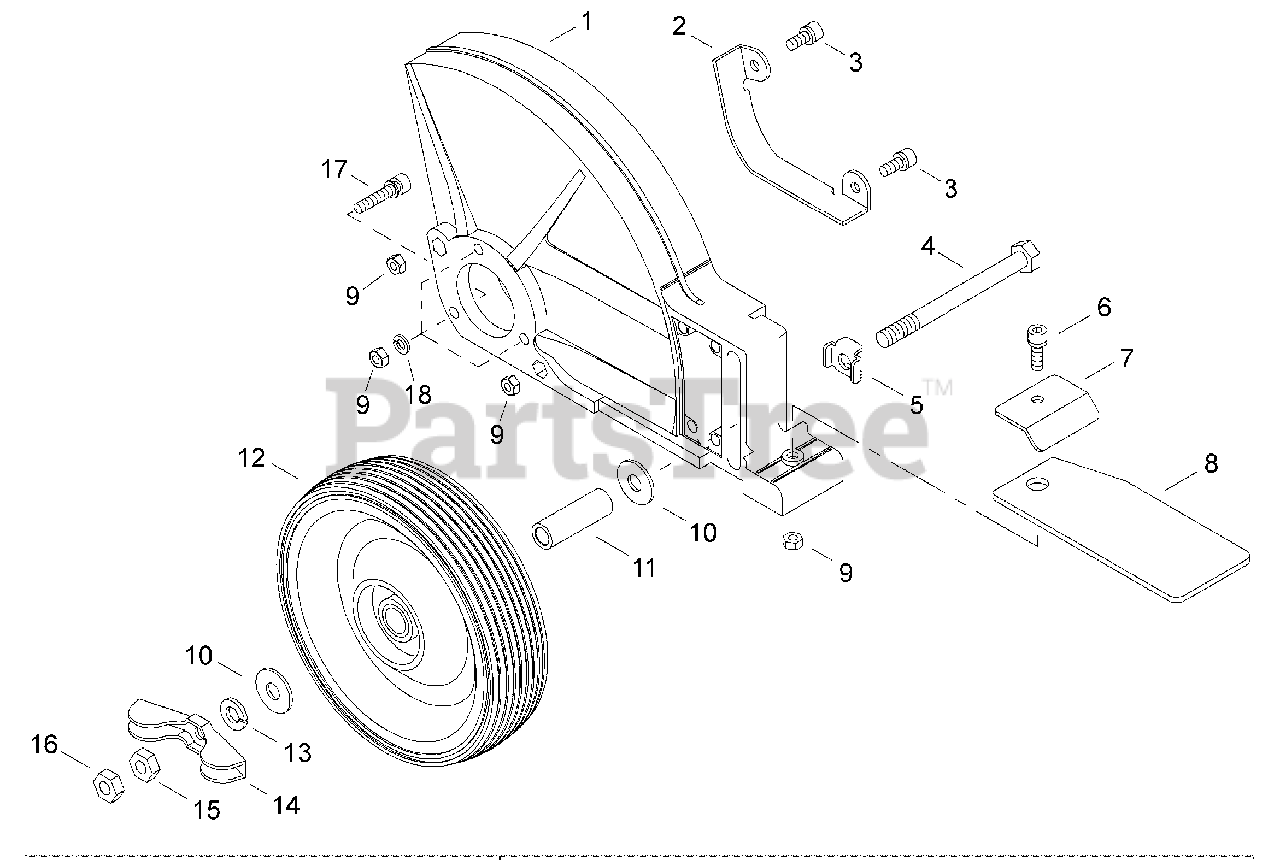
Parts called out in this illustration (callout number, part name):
1	SHIELD, BLADE
2	PROTECTOR, GEAR CASE
3	BOLT M5×12
4	BOLT M8×90
5	PLATE, LOCK
6	BOLT M5×16
7	PLATE, FLAP
8	FLAP, DEBRIS
9	NUT M5
10	WASHER
11	SLEEVE
12	WHEEL
13	WASHER, SPRING 8
14	KNOB, FASTENER
15	NUT M8
16	NUT, LOCK M8
17	BOLT M5×25
18	WASHER, SPRING 5
